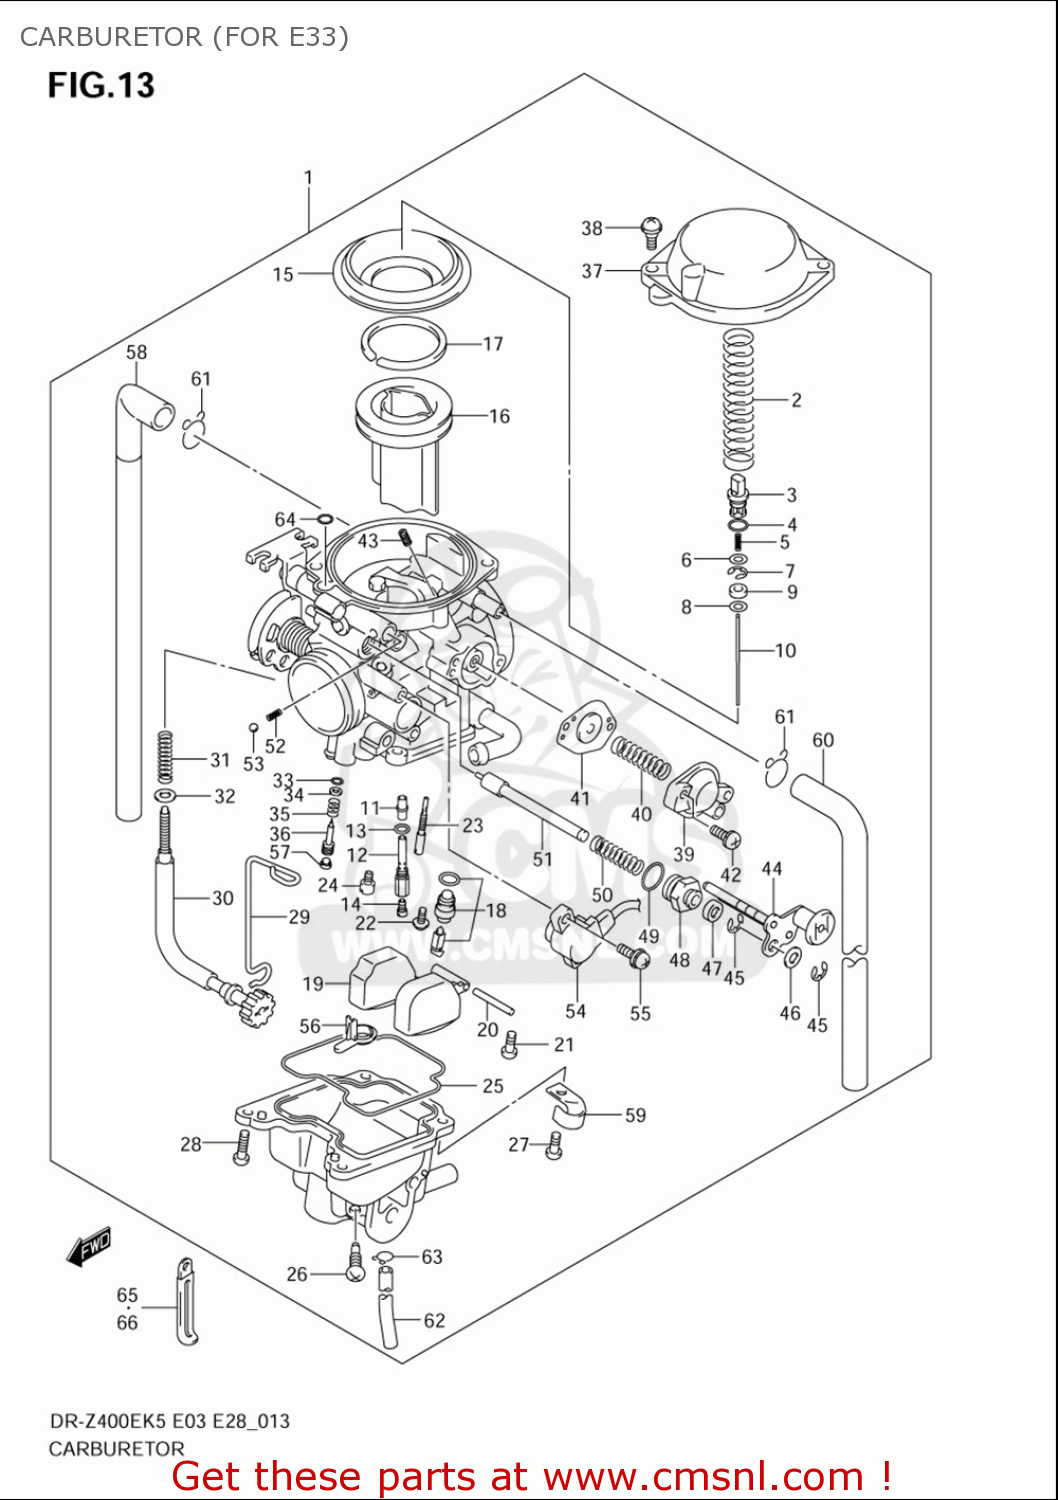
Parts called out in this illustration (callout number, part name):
1	CARBURETOR ASSY
2	SPRING
3	HOLDER
4	O RING(D:1.9,ID:4.8)
5	SPRING
6	WASHER
7	E RING,MULTIPLE JET NOZZLE
8	RING
9	WASHER
10	NEEDLE,JET
11	JET,NEEDLE
12	HOLDER,JET
13	O RING
14	JET,MAIN(140)
15	DIAPHRAGM
16	VALVE,PISTON
17	RING
18	VALVE ASSY,NEEDLE
19	FLOAT ASSY
20	PIN,FLOAT
21	SCREW
22	SCREW
23	JET,PILOT(22.5)
24	JET,MAIN(62.5)
25	GASKET (NAS)
26	PLUG,DRAIN
27	SCREW
28	SCREW
29	CLIP
30	SCREW,ADJUST
31	SPRING,THROTTLE SCREW
32	WASHER,STARTER SHAFT
33	O RING,PILOT AIR SCREW
34	WASHER
35	SPRING,THROTTLE SCREW
36	ADJUSTER
37	COVER,DIAPHRAGM
38	SCREW
39	COVER ASSY
40	SPRING
41	DIAPHRAGM ASSY
42	SCREW
43	JET,PILOT AIR(155)
44	PLATE ASSY
45	E RING
46	WASHER
47	CAP,STARTER VALVE
48	GUIDE SCREW,PLUNGER
49	O RING
50	SPRING
51	PLUNGER ASSY
52	SPRING
53	BALL,CARBURETOR
54	SENSOR ASSY
55	SCREW
56	RING
57	PLUG
58	PIPE,RUBBER
59	PLATE
60	HOSE,AIR VENT(6.5X10.5)
61	CLIP
62	HOSE,OVER FLOW(4.5X8X400)
63	CLIP
64	O RING
65	CLAMP(L:65)
66	CLAMP(L:120 T:1.0)
